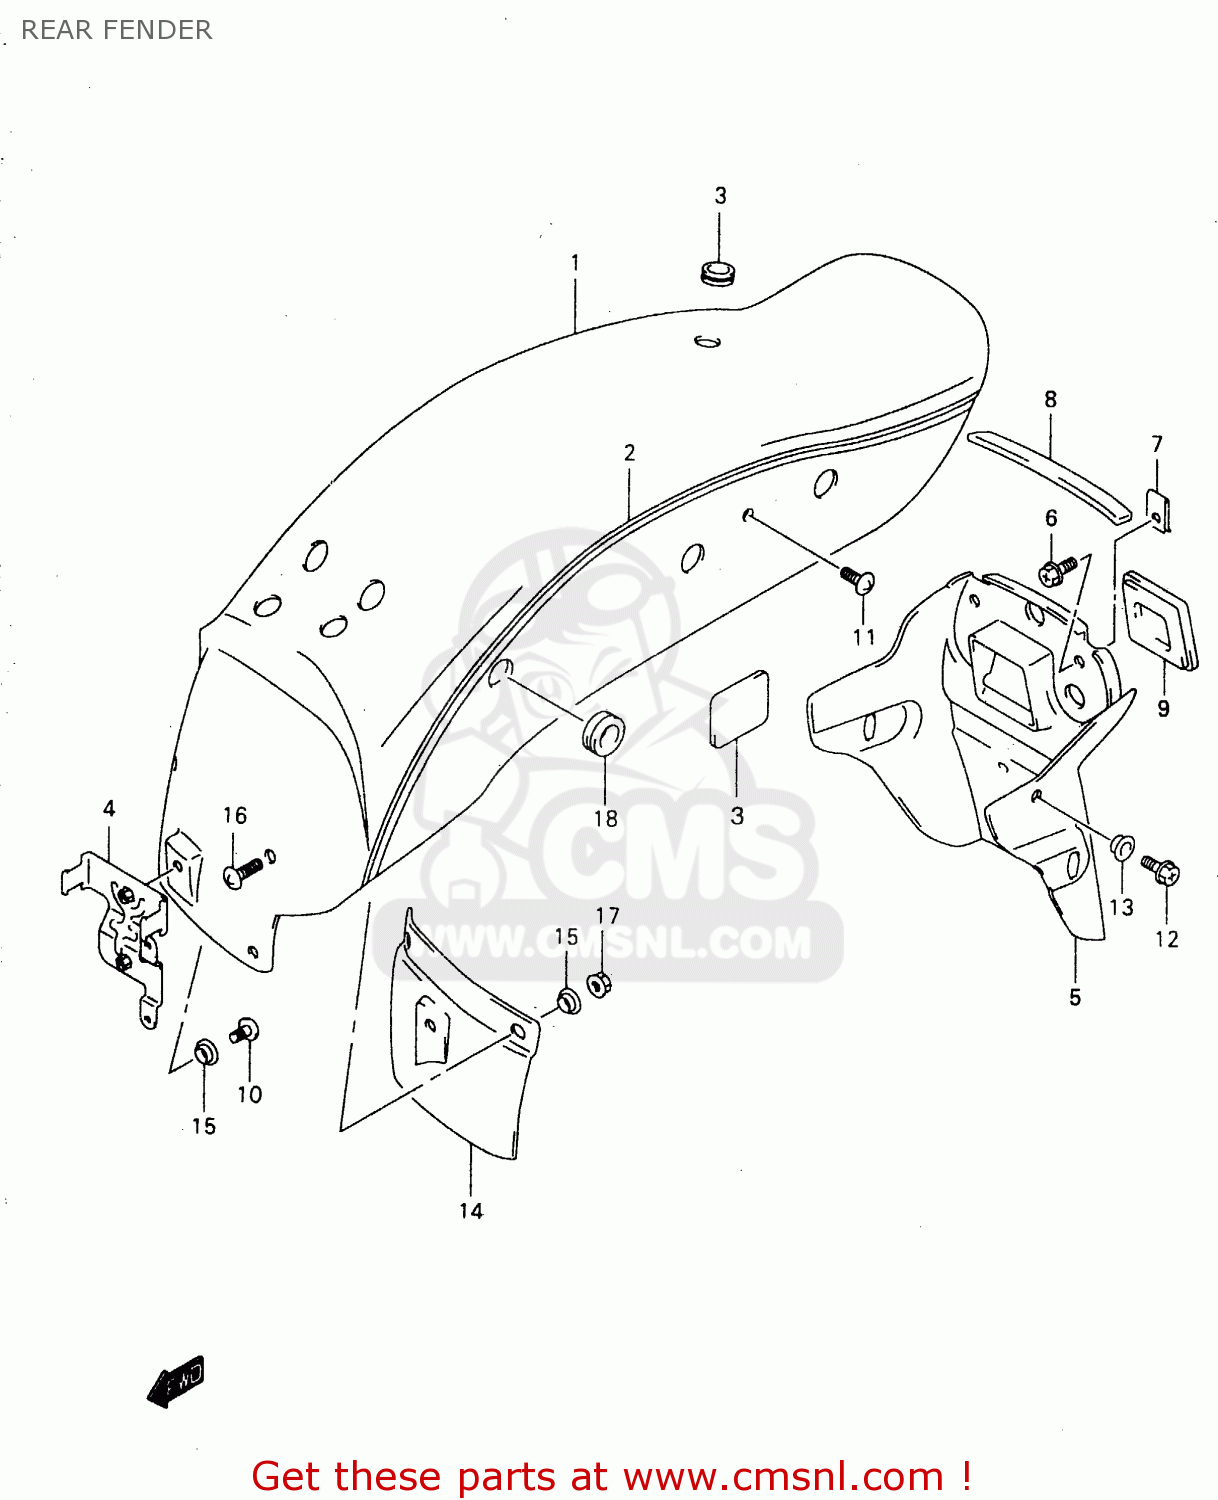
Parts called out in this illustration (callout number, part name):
1	FENDER,RR
2	TAPE SET,RR FENDER
3	CUSHION
4	BRACKET,RR FENDER
5	EXTENSION,RR FENDER
6	SCREW
7	PLATE,FRAME COVER
8	CUSHION,RR FENDER EXTENSION
9	CAP,RR FENDER EXTENSION
10	SCREW
11	SCREW 6X12
12	BOLT
13	WASHER
14	MUDGUARD,RR FENDER
15	WASHER
16	SCREW
17	NUT
18	CUSHION,RR FENDER
